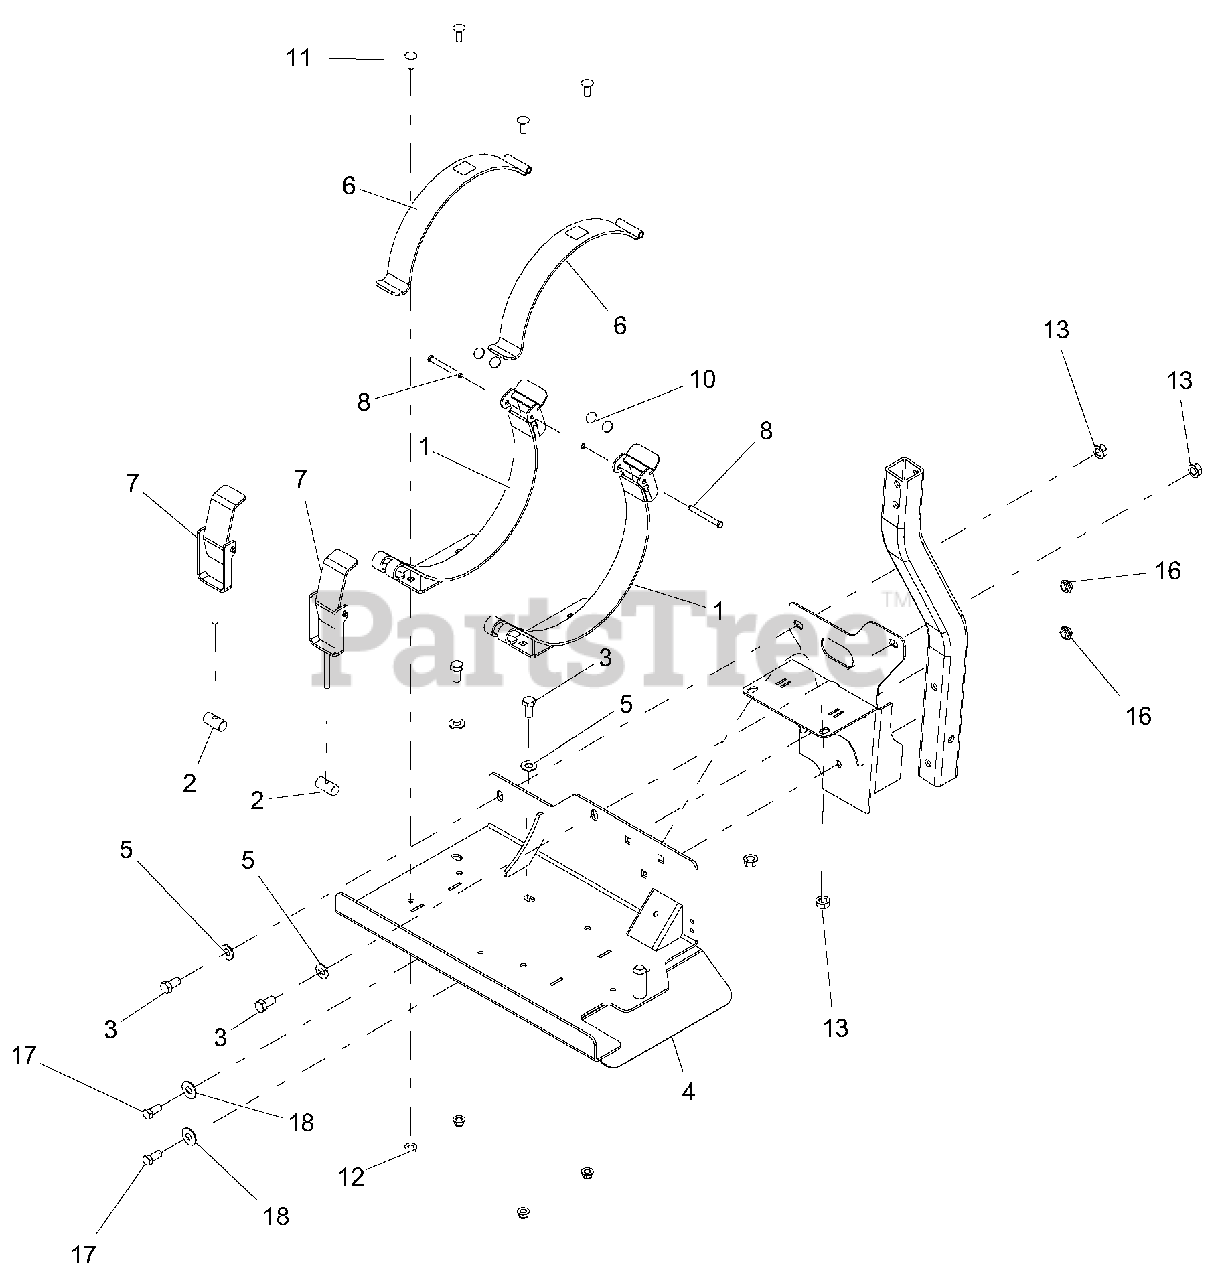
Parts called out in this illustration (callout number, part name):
1	WLDMT, CLAMP LP TANK
2	PIVOT, LP CLAMP HANDLE
3	BLT-HEX .50-13X1.00 GR5 YWZC
4	LH LP TANK MTG W/SAFETY DECAL
5	WSHR-FL-STL.531X1.06X.095YWZC
6	LP TANK CLAMP W/SAFETY DECAL
7	ASM, LP TANK HANDLE CLAMP
8	PIN, LP CLAMP
10	MAGNET, .75X.060, LP CLAMP
11	BLT-RDHDSQNK .38-16X1.00 G5 YWZC
12	NUT-LK-NYL-FLG .38-16 YWZC
13	NUT, LK-TOP-FLG .50-13 YWZC
16	NUT-LK-NYL-FLG .44-14 YWZC
17	BLT-HEX .44-14X1.00 GR5 YWZC
18	WSHR-FL-STL..50X1.25X.083 YWZ
